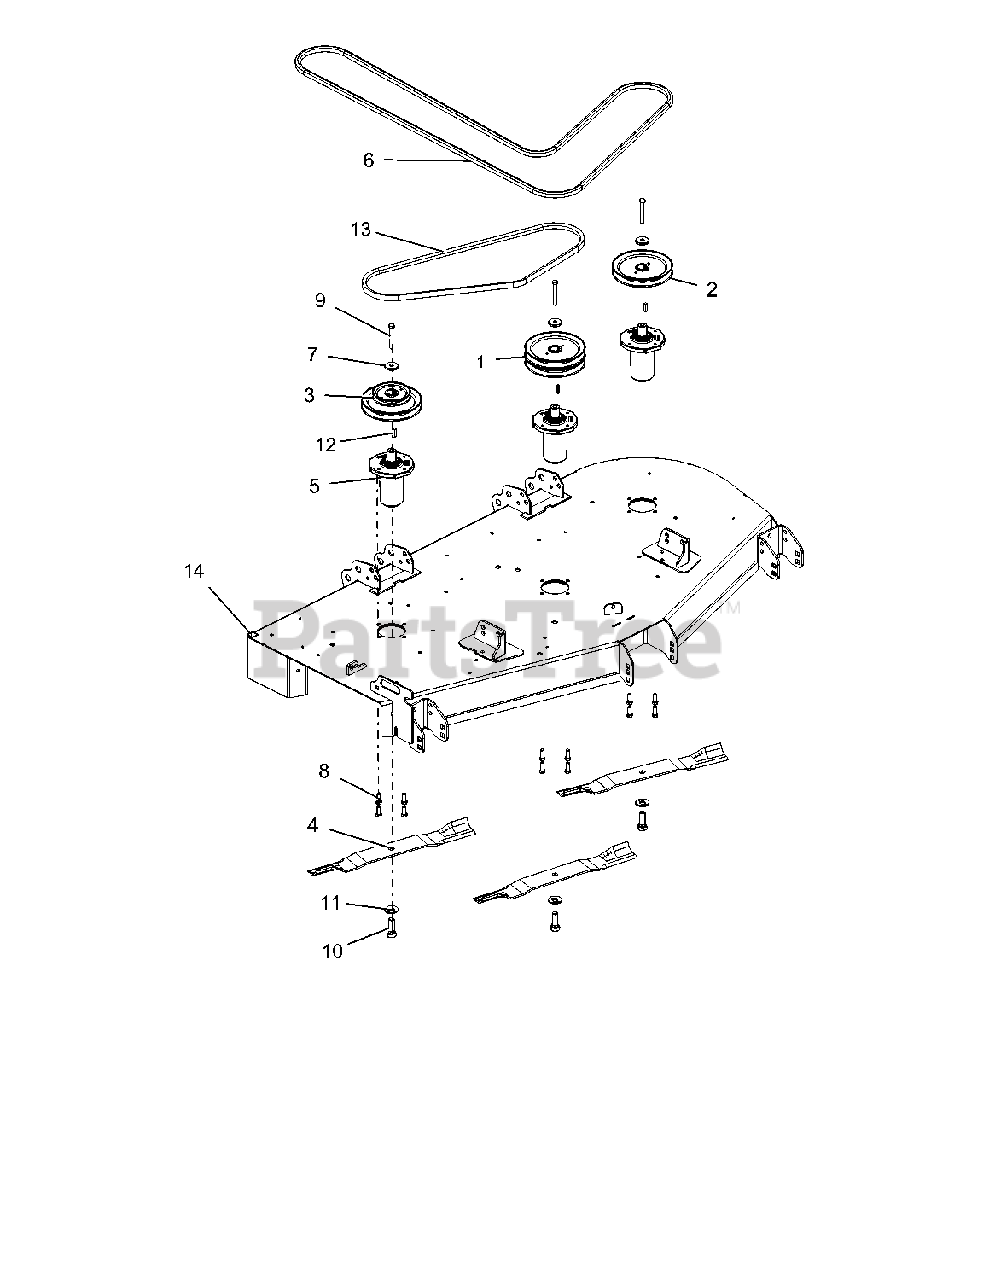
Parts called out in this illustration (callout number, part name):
1	PULLEY, DOUBLE 1"ID X 6.75"OD-BLACK
2	PULLEY, V-1" ID X 6.75" OD-BLACK
3	PULLEY, DOUBLE -1"X6.75"&4.25OD-BLACK
4	BLADE, 20.5"
5	SERVICE, ASM SPINDLE- DUCTILE
6	V-Belt, BB-Wrapped Clutching
7	RETAINER, SHEAVE SPINDLE
8	BLT-HEX .38-16X1.00 GR5 YWZC EP30
9	BLT-HEX .38-16X2.75 GR8 YWZC
10	BLT, HEX .62-18X1.75 GR8 YWZC
11	WSHR, BLVL .63X1.625X.14
12	KEY-SQ .250X.250X1.00 RC 40-50
13	BELT, B 63.00 RAW COGGED
14	KIT, 60" MOWER DECK W/SAFETY DECALS-RED
